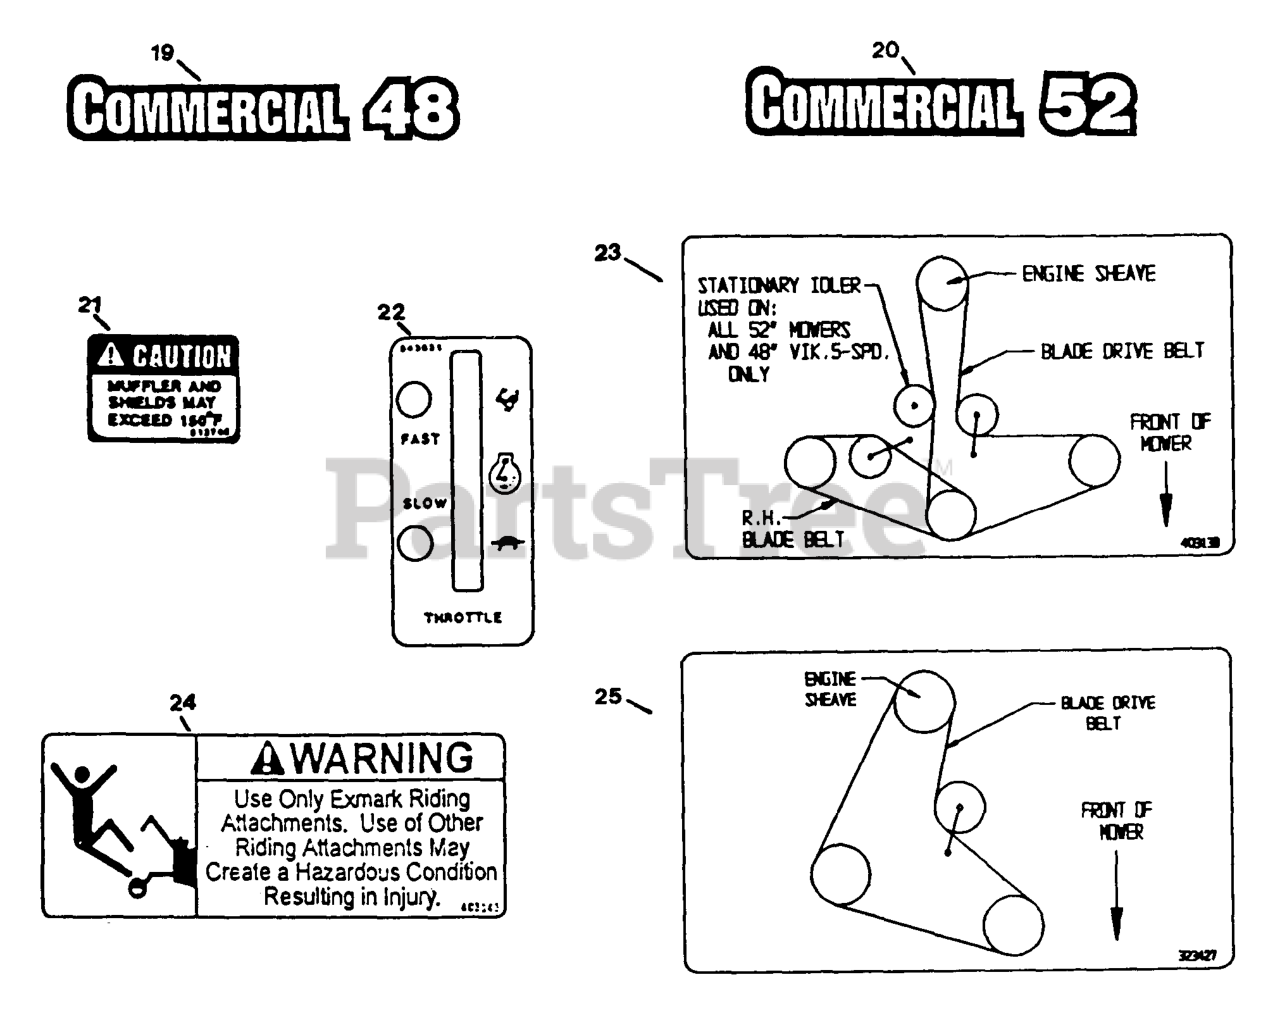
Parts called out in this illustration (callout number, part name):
19	DECAL,COMMERCIAL 48
20	DECAL,COMMERCIAL 52
24	DECAL,SULKY WARNING
25	DECAL,BELT ROUTING 32/36
